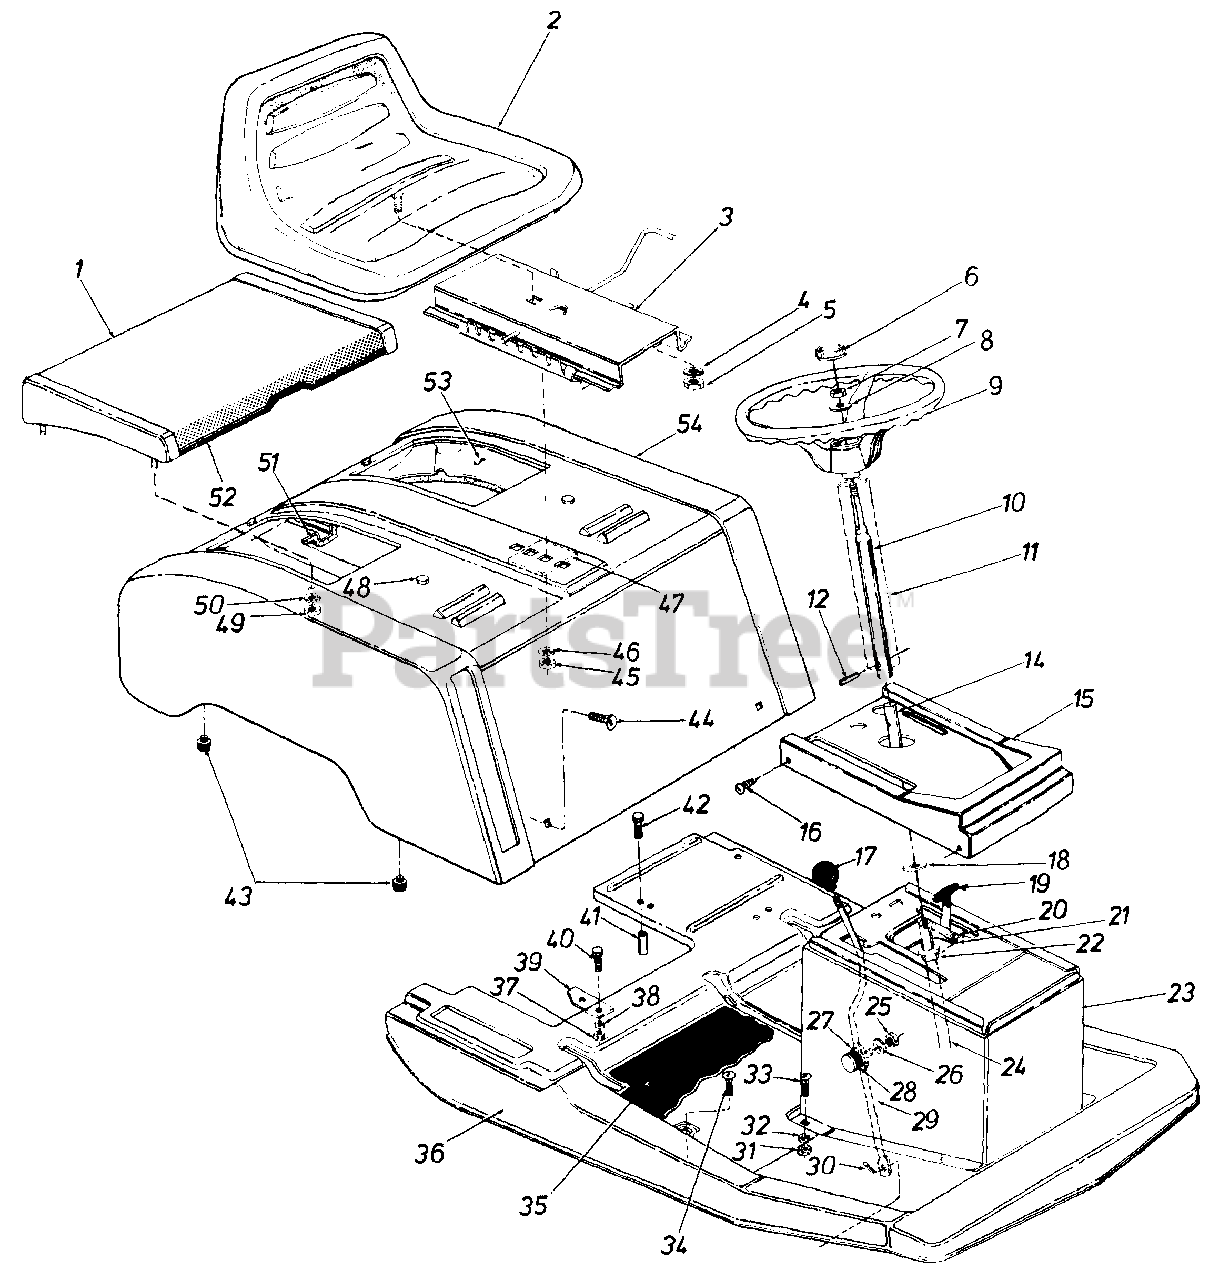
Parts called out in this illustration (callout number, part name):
1	Air Intake Screen
3	Seat Adjuster Comp.
4	L-Wash. 1/2" I.D.
5	Hex Nut 1/2-13 Thd.
6	Steering Wheel Cap
7	Hex Cent. L-Nut 5/16-18 Thd.
8	Belleville Washer
9	Steering Wheel
10	Adapter and Tube Ass'y.
11	Steering Tube Spacer
12	Spring Pin 1/4 Dia. x 1.50" Lg.
14	Steering Shaft
15	Console Center
16	Truss Mach. Scr. #10 x .50" Lg.
17	Ball Knob
18	Fl-Wash. .625 I.D. x 1.102 O.D.
19	Throttle Control - Comp.
20	Truss Mach. Scr. #10 x .50 Lg.
21	Speed Nut #10
22	Hex Flange Bearing
23	Center Console Ass'y.
24	Steering Shaft
25	Hex Ins. L-Nut 5/16-18 Thd.
26	Fl-Wash. .344 I.D. x .88 O.D.
27	Fl-Wash. .344 I.D. x .88 O.D.
28	Rubber Wash. .33 I.D. x .87 O.D.
29	Shift Lever
30	Cotterpin 3/32 Dia. x .75 Lg.
31	Hex Nut 5/16-18 Thd.
32	Belleville Washer. .345 I.D. x .885 O.D.
33	Carr. Bolt 5/16-18 x .62" Lg.
34	Carr. Bolt 5/16-18 x .62" Lg.
35	Floor Mat
36	Front Cover
37	Hex Nut 1/4-20 Thd.
38	L-Wash. 1/4 I.D.
39	Transmission Brkt.
40	Hex Scr. 1/4-20 x .50" Lg.
41	Spacer Tube
42	Hex Scr. 5/16-18 x 4" Lg.
44	Carr. Bolt 5/16-18 x .62" Lg.
45	Hex Nut 1/2-13 Thd.
46	L-Wash. 1/2 I.D.
47	Seat Mtg. Plate
48	Hex Scr. 1/4-20 x .50" Lg.
49	Hex Nut 1/4-20 Thd.
50	L-Wash. 1/4 I.D.
51	Air Duct Seal
52	Extruded "U" Channel - 18 1/4" Lg.
53	Air Intake Duct
54	Rear Cover Ass'y.
